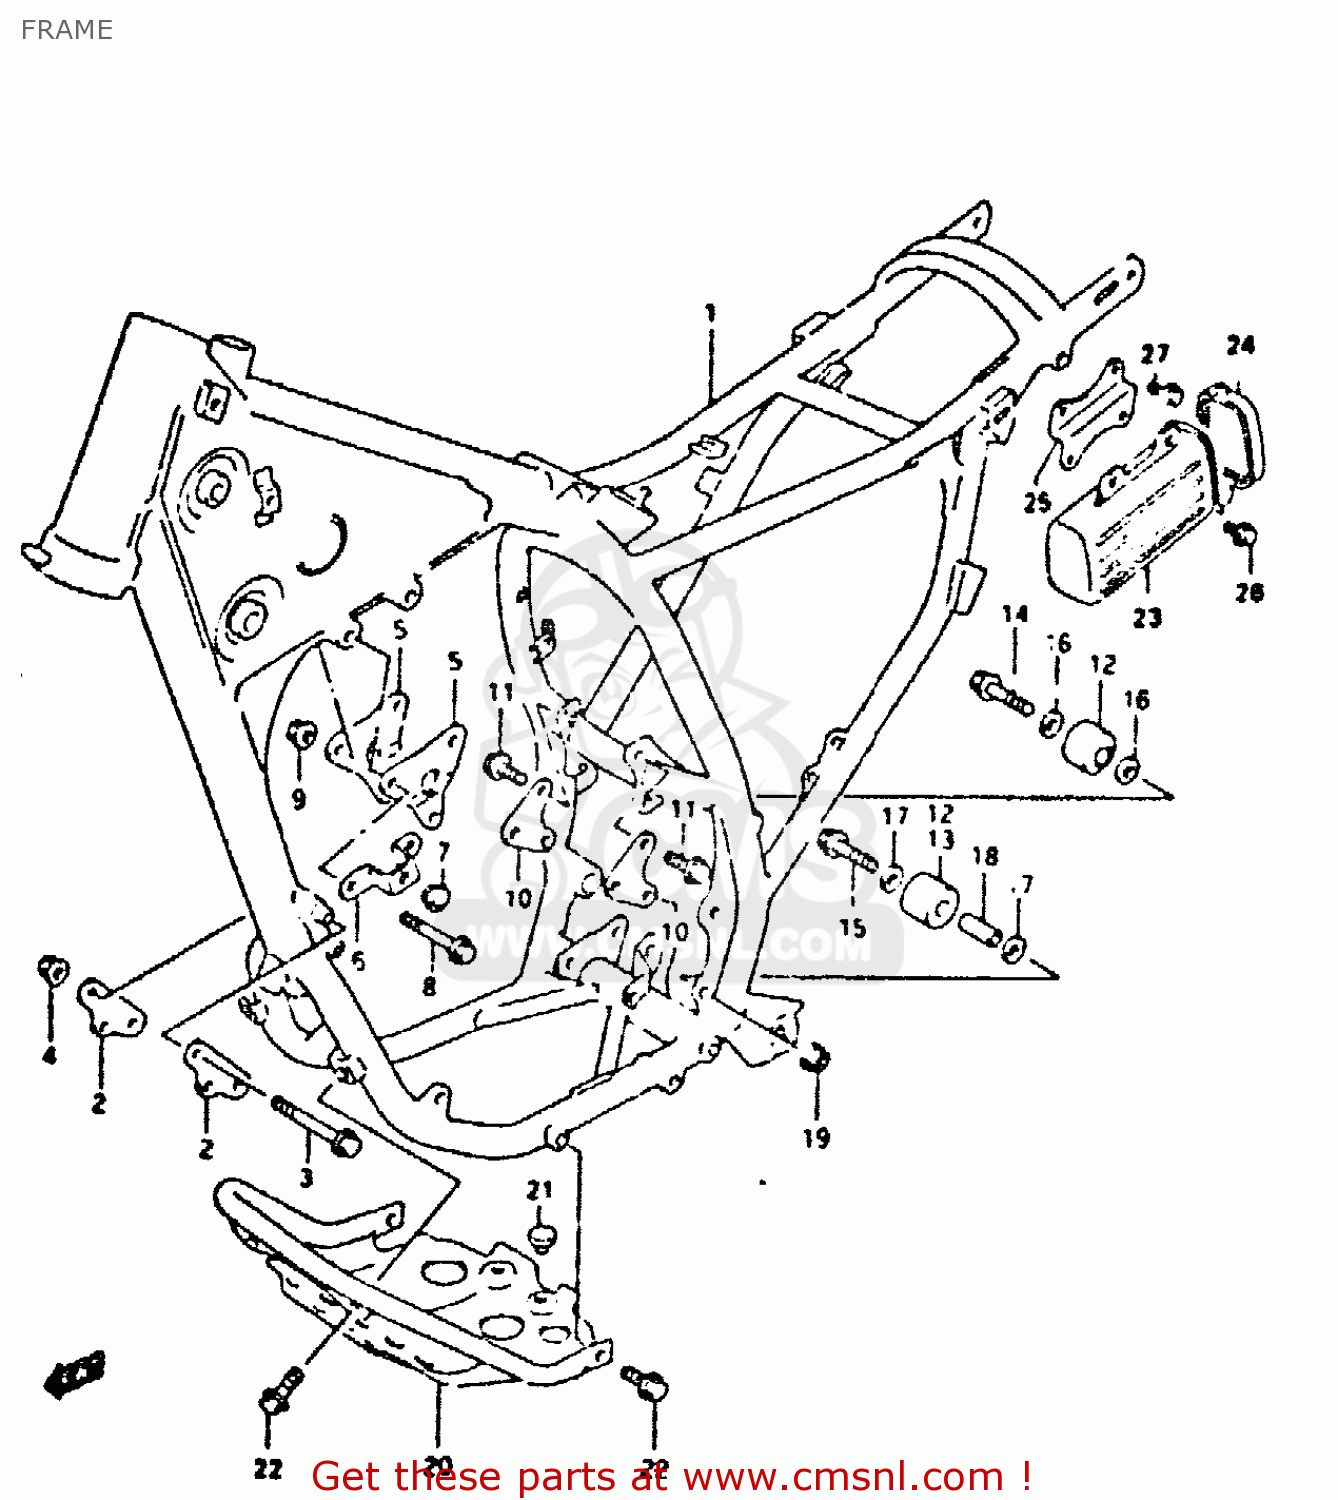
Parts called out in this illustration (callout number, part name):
1	FRAME
2	PLATE,ENGINE MOUNT FR
3	BOLT(8X85)
4	NUT
5	PLATE,ENGINE MOUNT UPR
6	PLATE,FUEL TANK STOPPER
7	CUSHION
8	BOLT(8X70)
9	NUT
10	PLATE,ENGINE MOUNTING,REAR
11	BOLT(8X16)
12	ROLLER,CHAIN
13	ROLLER,CHAIN CONTROL
14	BOLT(8X38)
15	BOLT
16	WASHER
17	WASHER
18	SPACER (8.6X13.8X28)
19	NUT
20	PROTECTOR,ENGINE
21	CUSHION
22	BOLT
23	HOLDER,TOOL
24	CAP,TOOL HOLDER
25	PLATE,TOOL HOLDER FITING
26	BOLT 6X16
27	BOLT
